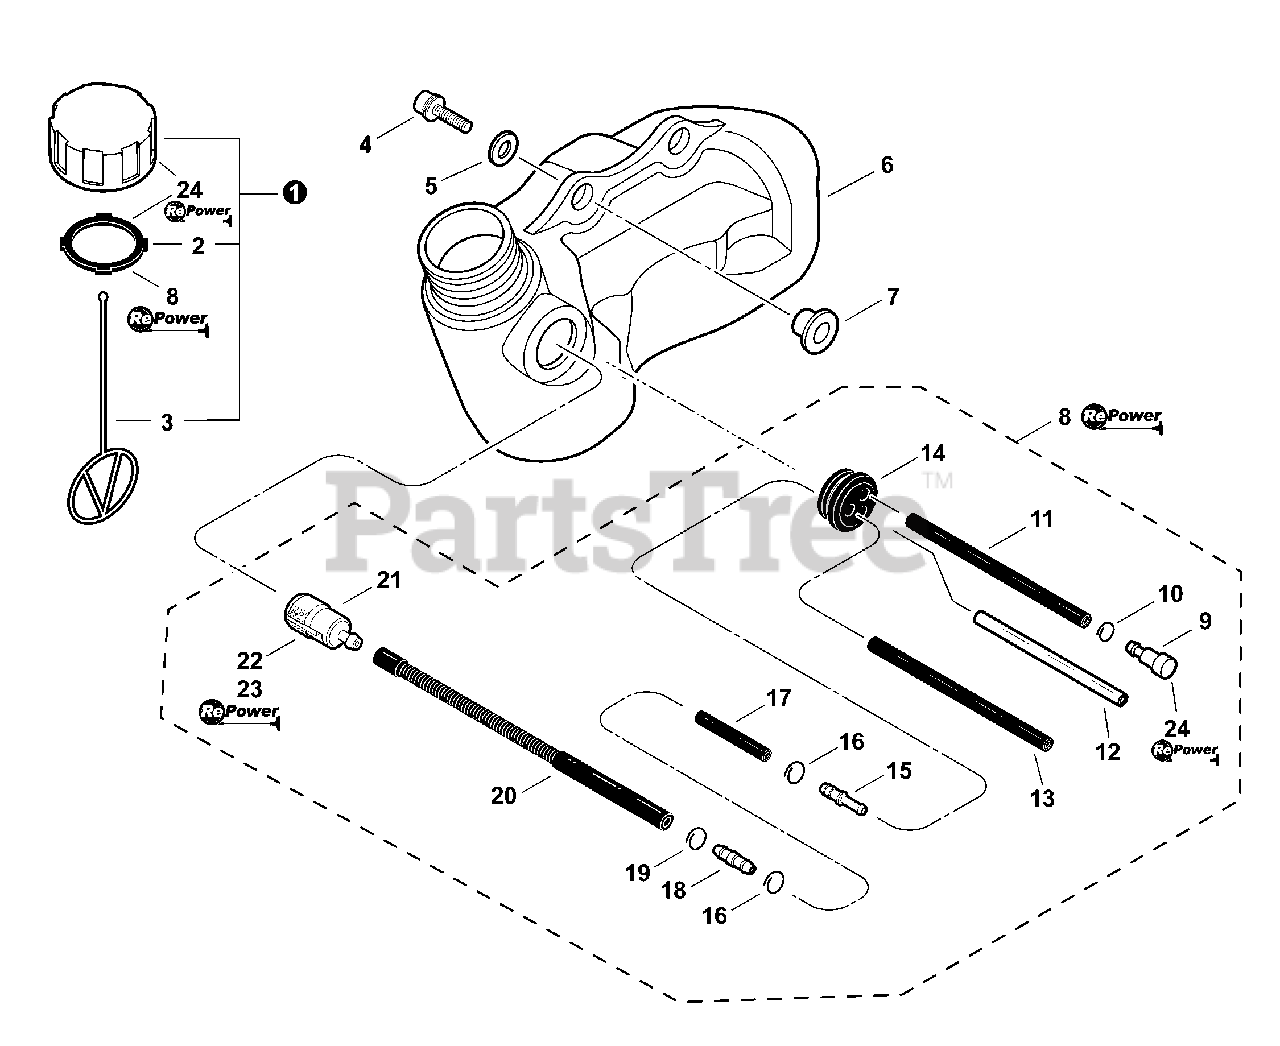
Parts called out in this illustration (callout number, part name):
1	CAP ASSY
2	GASKET, CAP
3	CONNECTOR, CAP
4	SCREW - 5×20
5	WASHER - 5
6	TANK, FUEL
8	RePower FUEL SYSTEM KIT
9	VENT, FUEL TANK
10	CLIP - 6
11	PIPE - 3×6×50 -- BLACK
12	PIPE - 3×6×75 -- CLEAR
13	PIPE, UPPER - 3×5×61 -- BLACK
14	GROMMET
15	CONNECTOR, FUEL PIPE
16	CLIP - 6.5
17	PIPE - 3×6×35 -- BLACK
18	CONNECTOR, PIPE
19	CLIP - 6.6
20	PIPE, FUEL - CORRUGATED
21	FILTER, FUEL
22	RePower FILTER KIT
23	RePower TUNE-UP KIT
24	Repower CAP AND VENT KIT
